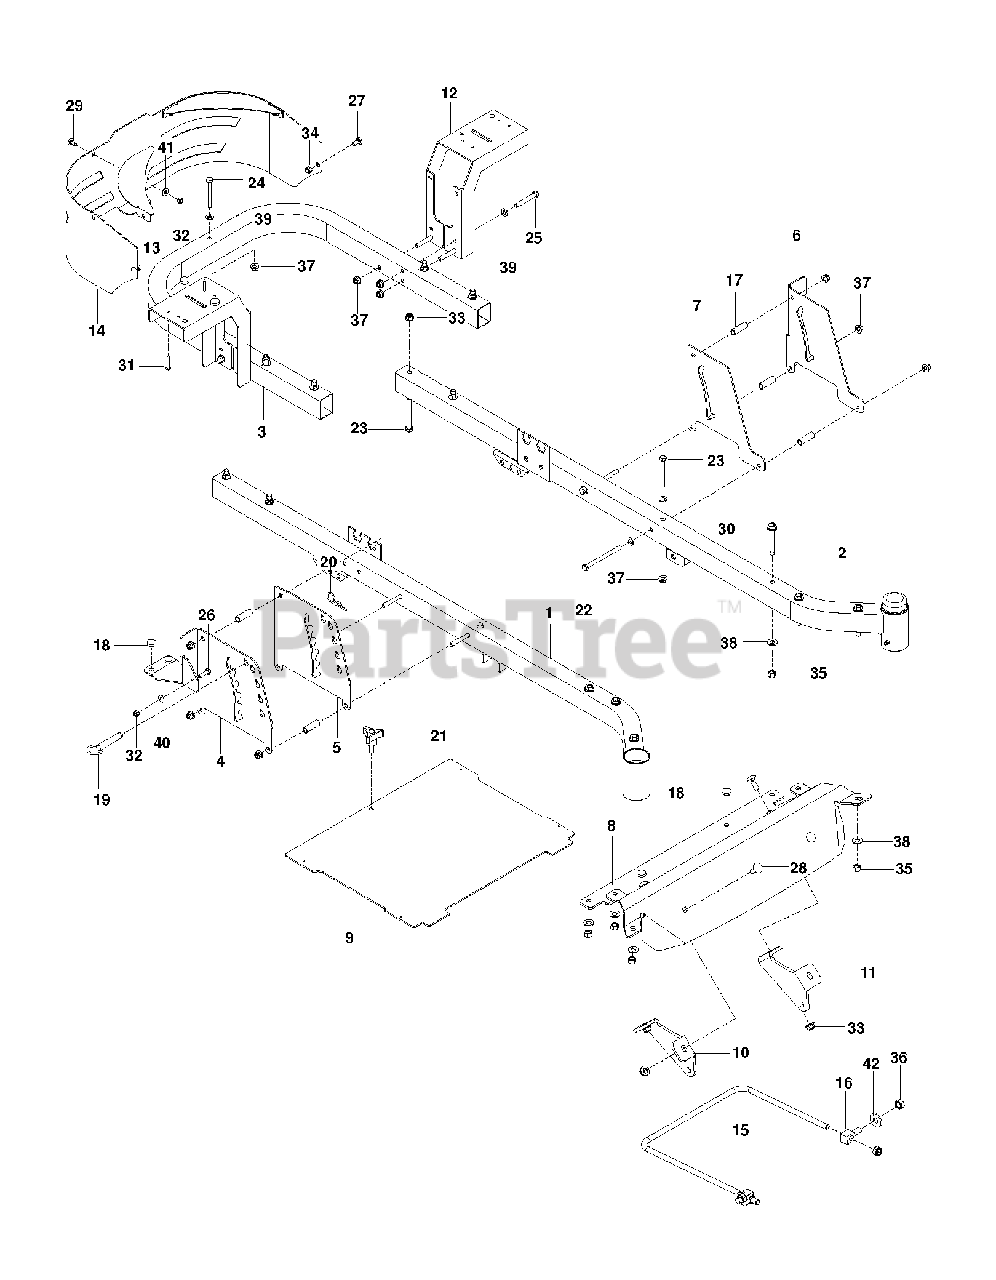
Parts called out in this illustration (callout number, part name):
1	FRAME, RT, ORANGE
2	FRAME, LT, ORANGE
3	FRAME TUBE, REAR, ORANGE
4	PLATE, DECK HEIGHT, BLK EZ
5	PLATE, DECK HEIGHT, BLACK
6	PLATE, OUTER BRAKE, BLACK
7	PLATE, BRAKE LATCH, BLACK
8	FOOT REST WIDE ORG
9	PLATE, FOOT W/DECALS EZ
10	MOUNT, STRUT, RT, BLK
11	MOUNT, STRUT, LT, BLK
12	SUPPORT, FENDER, BLACK
13	SUPPORT, CORNER, ORANGE
14	GUARD, REAR, ORANGE
15	LINK, FRONT SUSP.
17	SPACER, .334 ID X .5 OD X 1.5
18	GROMMET, BUMPER
20	HAIRPIN #4
21	KNOB W/STUD
22	HCS 5/16C X 4
23	HCS 3/8C X 3
24	HCS 5/16C X 2-3/4
26	HCS 1/4C X 1
27	BOLT 5/16C X 3/4" CARRIAGE
28	RHSNB 3/8C X 1
29	RHSSNB, 1/4-20X5/8
30	ENGINE BOLT, SPECIAL
31	SCR #10-12X1-1/2HEX WASH HD ZD
32	RP_NUT 1/4-20 NYLOC
33	NUT 3/8-16 HEX FLG NYLOC ZD
34	NUT 5/16 NYLOC
35	NUT HEX 3/8-16 NYLON, THIN
36	7/16-14 HEX NUT W/NYL RING ZD
37	5/16-18 NYLOC FLANGE NUT
38	RP WASHER 3/8 FLAT
39	FLAT WASHER 5/16 SAE
40	WASHER 1/4 SAE
41	WASHER 1/4 FLAT
42	WASH USS FLAT 1/2
